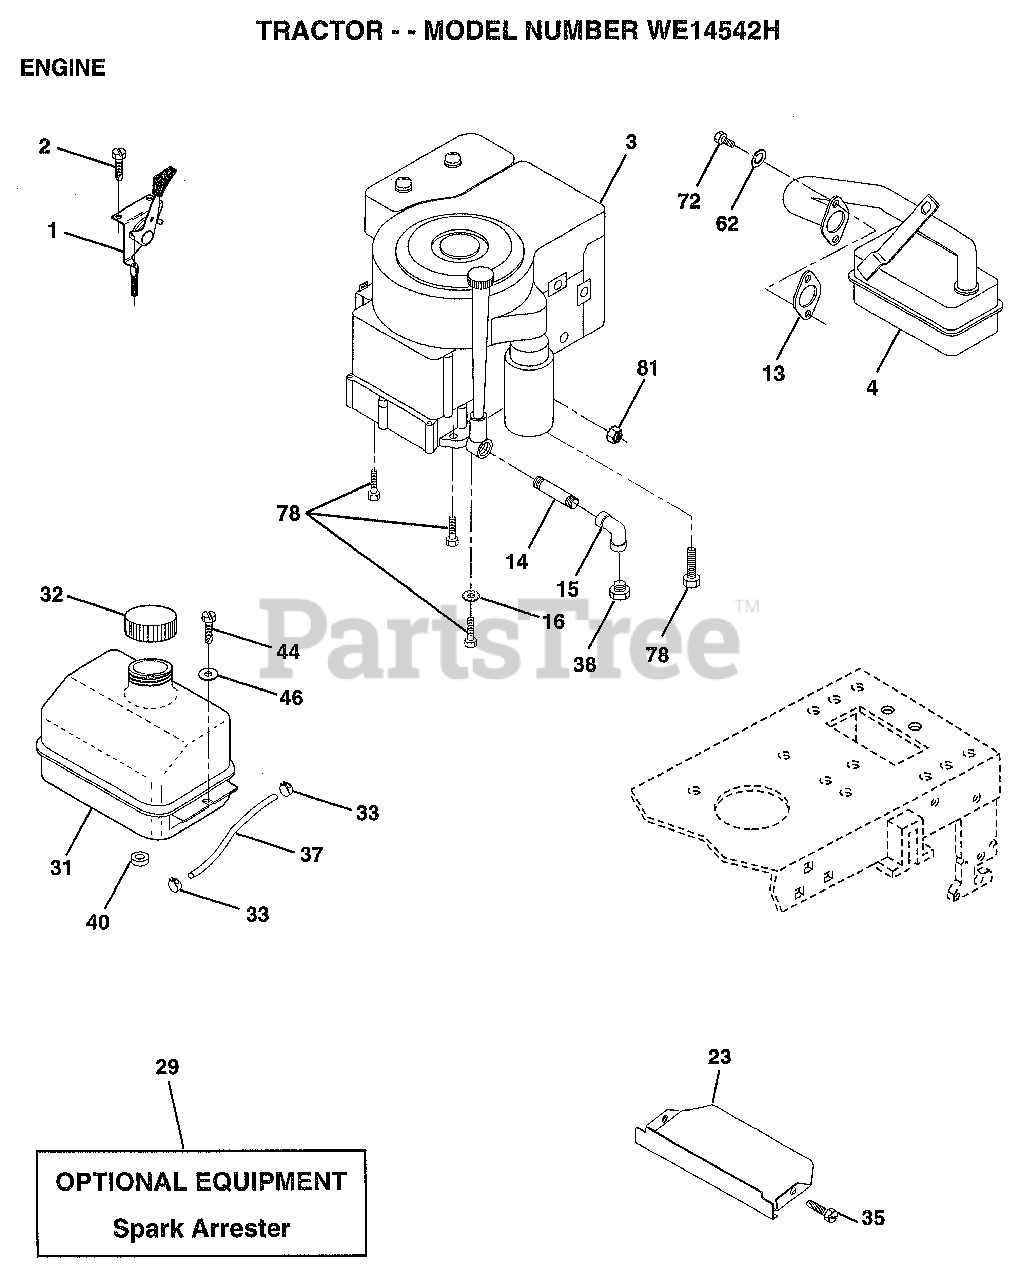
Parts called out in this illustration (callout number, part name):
1	CONTROL THROTTLE
2	SCREW LT
4	MUFFLER
13	GASKET ENG 1 313 LD TIN PLATED
14	PIPE NIPPLE
15	ELBOW
16	LOCKWASHER
23	SHIELD.BRN/DBR.GD
31	TANK.FUEL.LT.
32	CAP ASM FUEL
33	HOSE CLAMP
35	SCREW
37	LINE FUEL
44	SCREW HEX CRT
46	WASHER
62	LOCKWASHER
72	SCREW
78	SCREW
81	NUT
